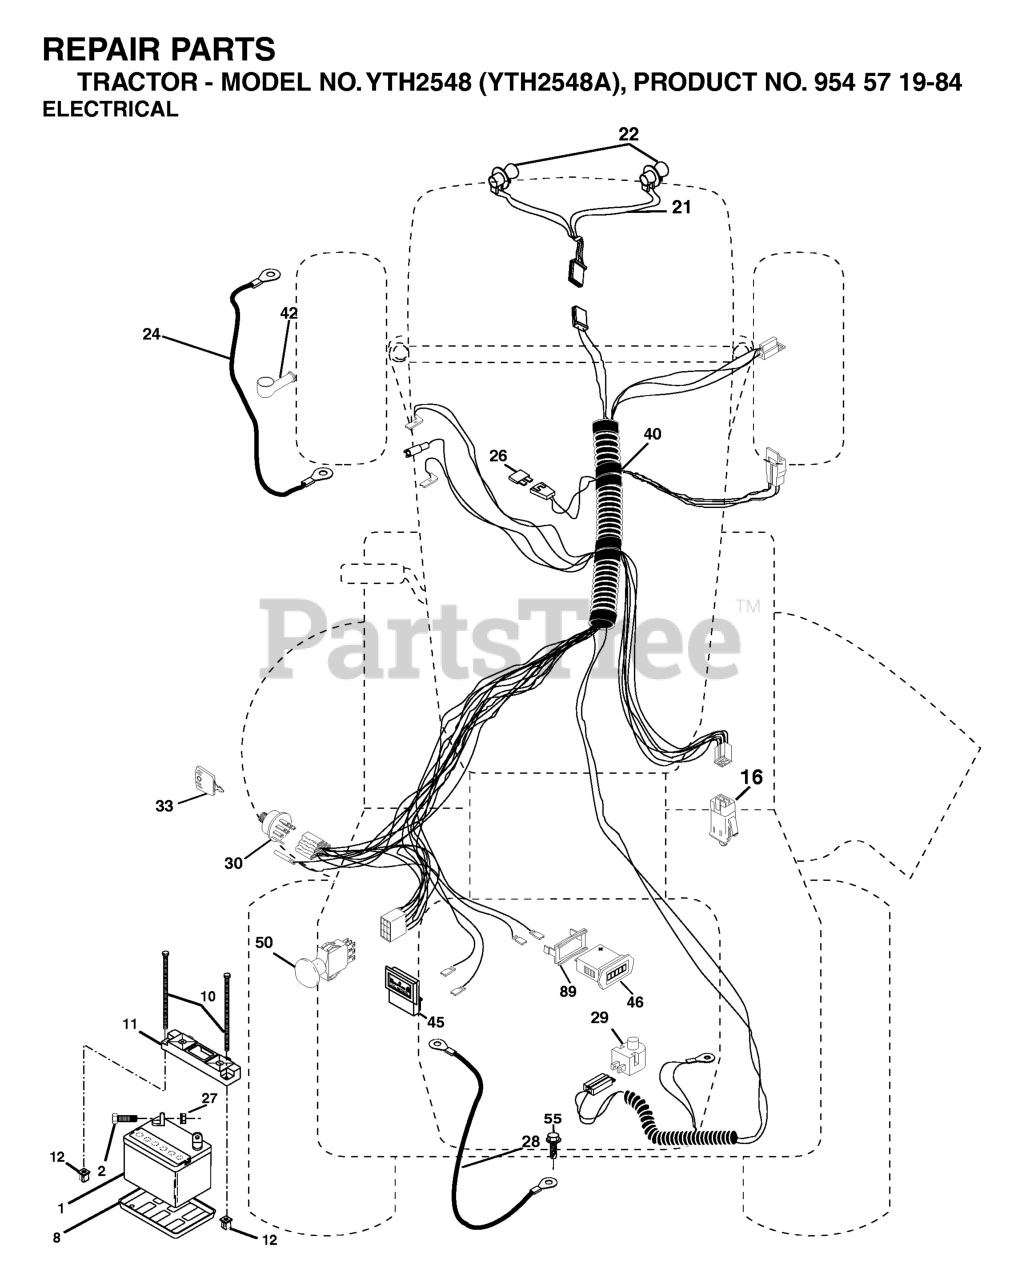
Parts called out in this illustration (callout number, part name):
1	BATTERY 12V .35 AMP
2	BOLT.HEX.1/4.X.3/4.DICHROMATE
8	BATTERY TRAY T
10	BOLT 1/4-20 X 7.5
11	BATTERY HOLDDOWN FRONT MOUNT
12	NUT, PUSH NYLON 1/4" BATTERY
16	SWITCH INTERLOOK PUSH-IN
21	HARNESS ASSY LIGHT
26	FUSE 20AMP
27	NUT
28	CABLE GROUND 6 GA 21" 90T BLK
29	RP.SWITCH.PLUNGER.NC.GRAY
30	IGNITION SWITCH
33	KEY MLD GEN DELTA
42	COVER.TERMINAL.RED
46	HOUR METER
50	RP.PTO.SWITCH.8 TERMINAL.BLACK
55	Screw 5/16-18 x 1/2 Hex, Self Tapping 5/16-18 x 1/2
89	BRACKET SNAP-IN HOURMETER
